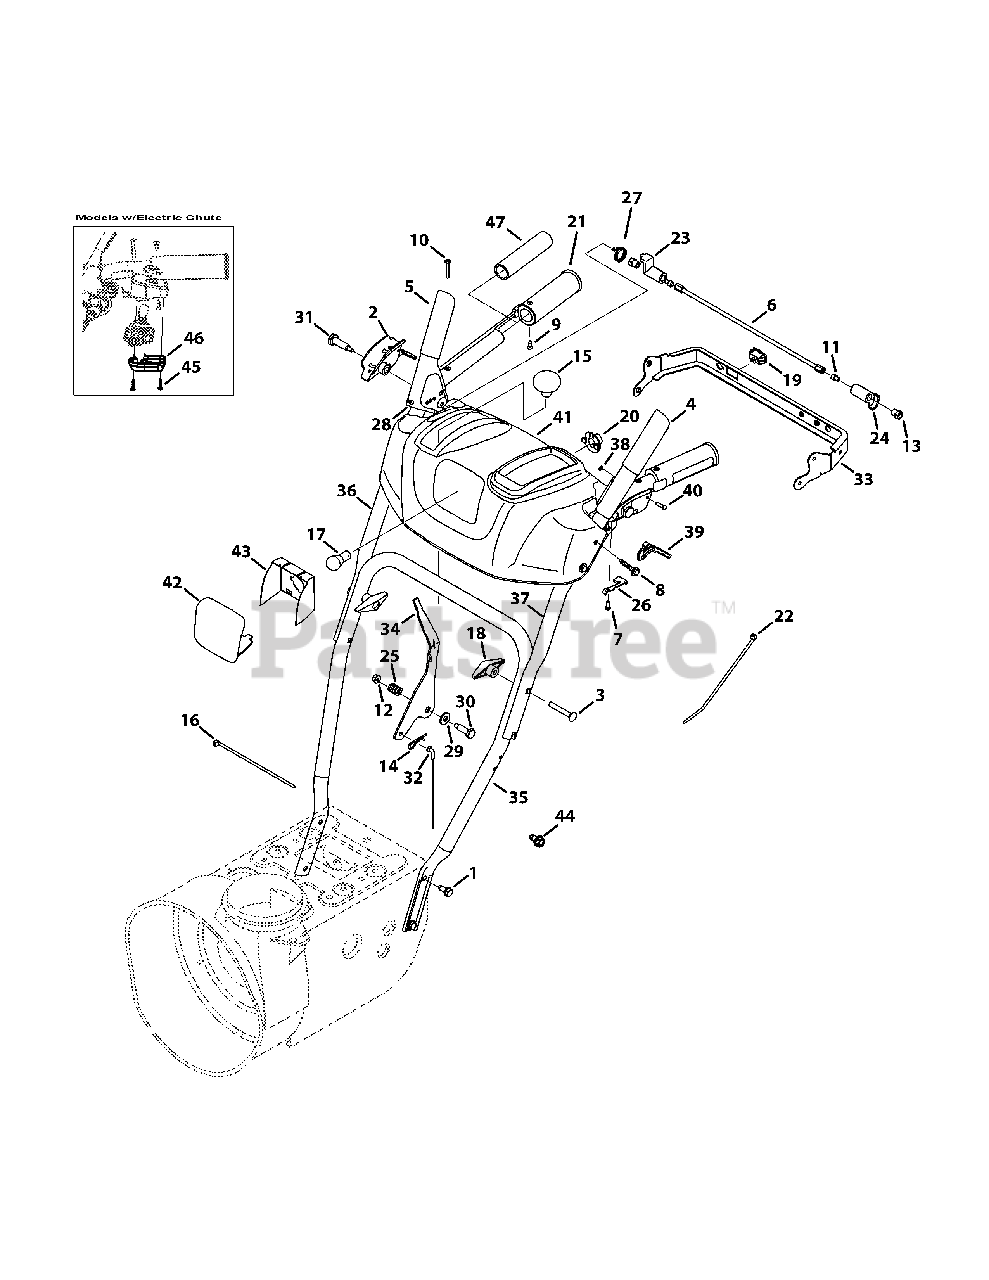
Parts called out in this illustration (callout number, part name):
1	Screw, Taptite, 5/16-18 x .750
2	Clutch Lock, RH
2	Clutch Lock, LH
3	Screw, Carriage, 5/16-18 x 2.50
4	Auger Engage, Black, LH
5	Drive Engage, Black, RH
7	Screw, Plastite, 8-16 x .50
8	Screw, Taptite, 1/4-20 x 1.625
9	Screw, 10-16 x 0.625
10	Screw, 10-24 x 1.375
11	Screw, 1/4-20 x .50
12	Nut, Flangelock, 1/4-20
13	Nut, Hex, 1/4-20
14	Click Pin, .092 x 1.64
15	Shift Knob
16	Cable Tie, 7"
18	Wing Knob, 5/16-18
19	Heated Grip Switch
20	Lamp Socket
21	Heated Grip
22	Cable Tie, Push Mount
23	Plate, Lock
24	Cam, Clutch Lock
25	Compression Spring, .39 x .60 x .88
26	Clutch Lock Spring
27	Torsion Spring, 0.8156 x .3038
28	Rubber Bumper
29	Washer, Flat, .385 x .87
30	Screw, Shield, .374 x 1.05
31	Screw, Shoulder, .437 x 1.345 x 1/4-20
32	Speed Selector Cable
33	Panel Bracket
35	Lower Handle
36	Upper RH Handle
37	Upper LH Handle
39	Steering Trigger Control, Black
40	Steering Trigger Pin, 3/16
41	Handle Panel
42	Lens Panel
43	Lens Label
44	Screw, TT, 1/4-20 x .500 (For ground wire)
45	Screw, .159 OD x .610
46	Housing Cover (Elec Chute)
47	Grip, 1.0 ID x 5.0 LG
